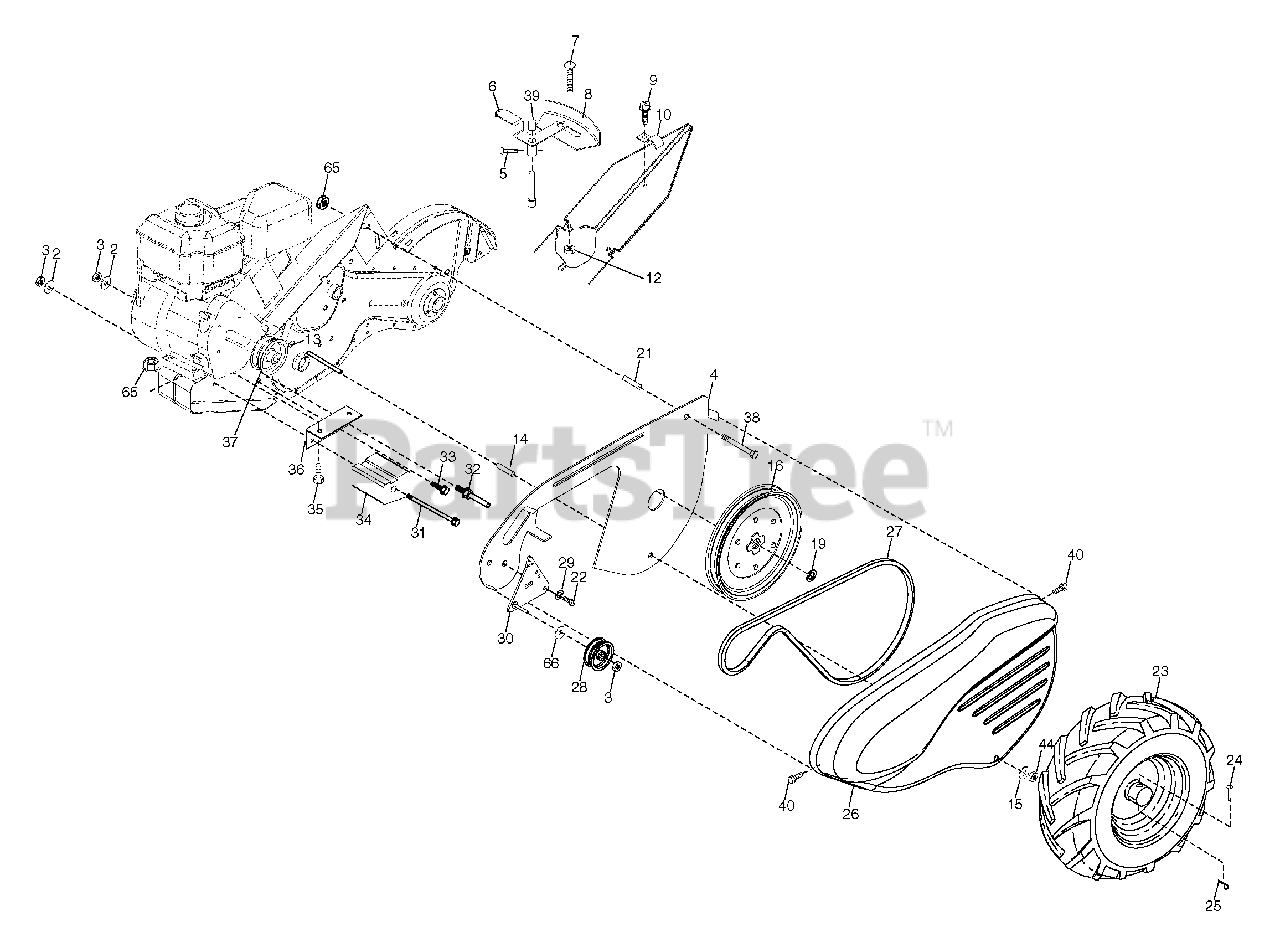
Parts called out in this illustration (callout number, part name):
2	Washer, Lock 3/8
3	Nut, Hex 3/8-16
4	Shield, Inner, Belt Guard
5	Pin Spirol Flared
6	Lever, Shift
7	Bolt, Carriage 1/4-20 x 1/2 Gr. 5
8	Plate, Shift Indicator
9	Screw, Hex, Washer Head, Slotted #10-24 x 1/2
10	Clip
12	Nut, Keps Hex 1/4-20 unc
13	Screw, Set, Hex 5/16-18 x 3/8
14	Spacer, Split 0.327 x 0.42 x 1.220
15	Washer 11/32 x 11/16 x 16 Ga.
16	Sheave, Transmission
19	Ring, Retainer
21	Spacer, Split 0.327 x 0.42 x 2.09
22	Bolt Hex 5/16-24 x 1/2
23	Tire
23	Rim
23	Tire Valve
24	Rivet, Drilled
25	Clip, Hairpin
26	Guard, Belt
27	Belt, V
28	Pulley, Idler
29	Ring, Klip
30	Bracket, Idler
31	Bolt, Hex 5/16-16 x 12
32	Shaft, Idler Arm
33	Bolt, Hex 3/8-16 x 1
34	Counterweight, L.H.
35	Bolt, Hex 5/16-18 x 1-1/2
36	Bracket, Reinforcement, L. H.
37	Sheave, Engine
38	Bolt, Hex 5/16-18 x 2-3/4
39	Cap, Plunger
40	Screw, Hex Wsh Slt #10-24 x .50
44	Nut, Lock 5/16-18
65	Nut, Lock Hex Flange
66	Washer 13/32 x 13/16 x 12 Ga.
